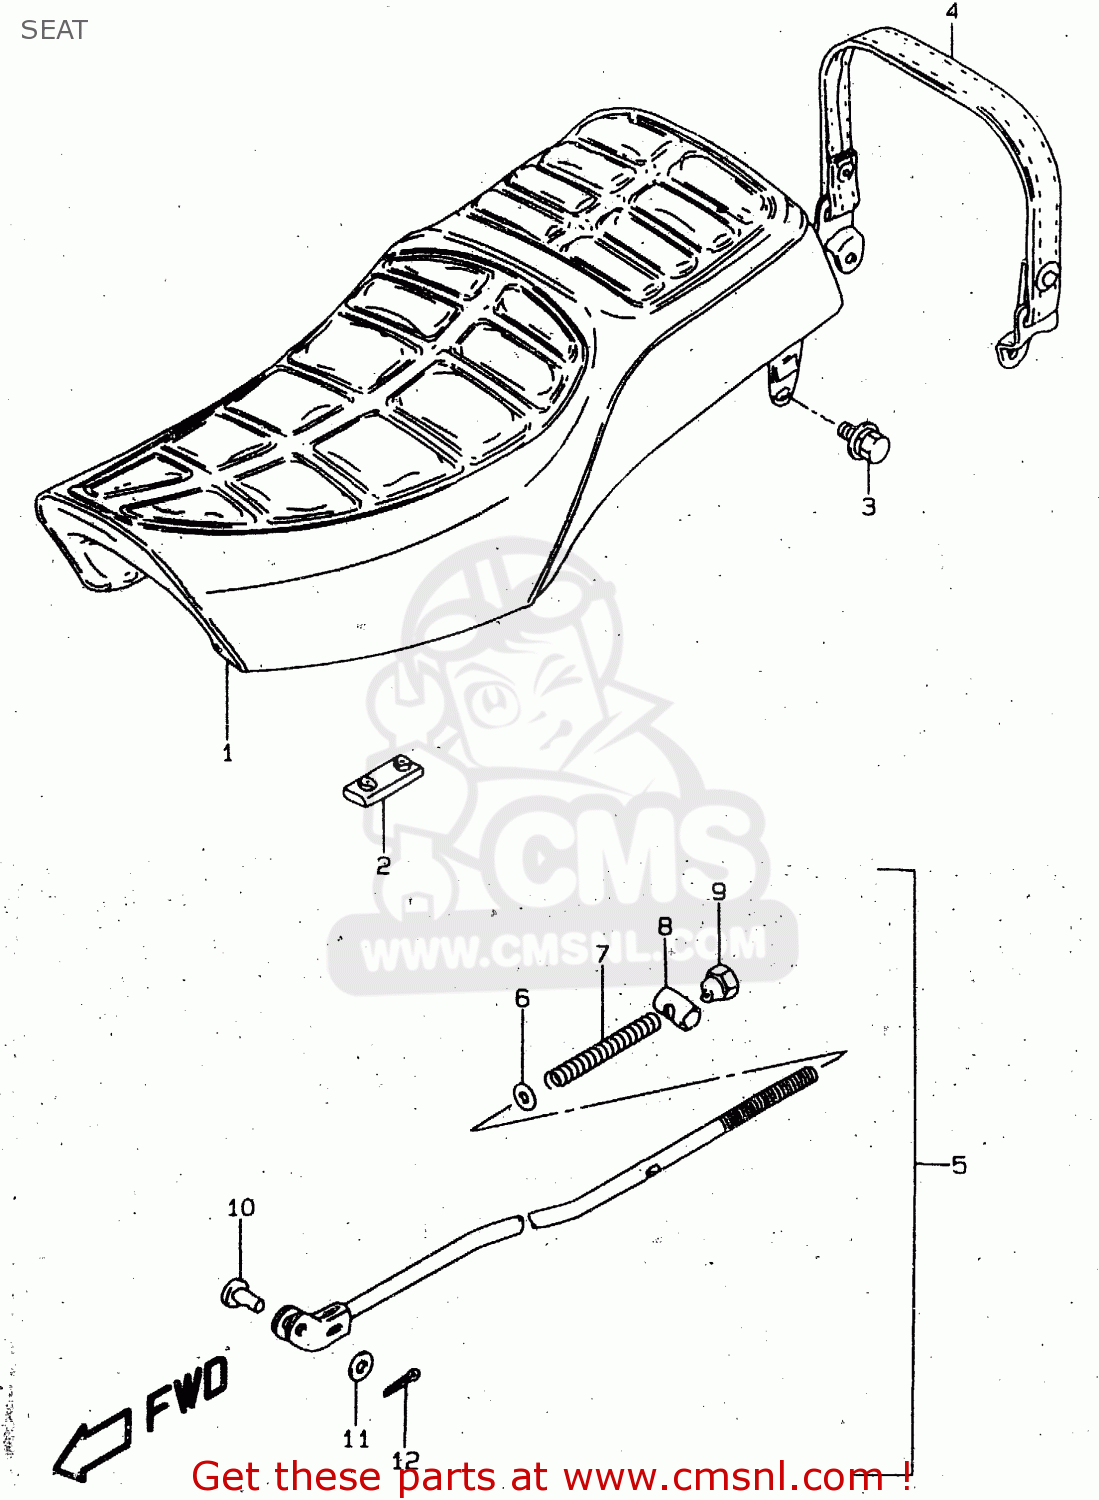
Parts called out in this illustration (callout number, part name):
1	SEAT ASSY
2	CUSHION
3	BOLT
4	BAND ASSY,SEAT GRIP
5	ROD ASSY,RR BRAKE
6	WASHER
7	SPRING
8	PIN(11X18)
9	NUT
10	PIN(L:13.5)
11	WASHER
12	PIN 20X20
